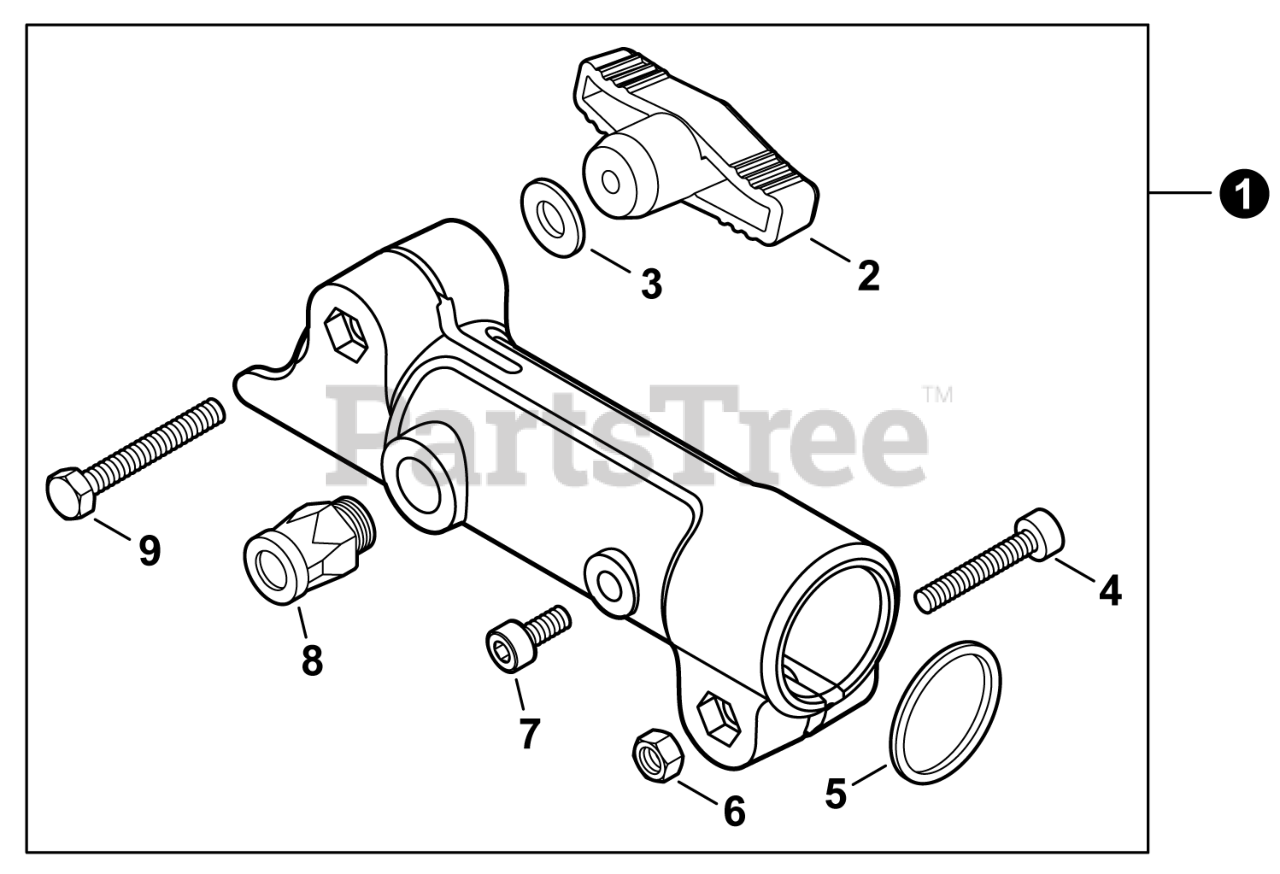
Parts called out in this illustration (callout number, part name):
1	COUPLER ASSY
2	THUMBSCREW
3	WASHER 6.6x20x1.6
4	BOLT, TORX 6x25
5	WASHER 18 SPR STEEL
7	BOLT, TORX 5x10
8	LATCH ASSY
9	BOLT 6x40
